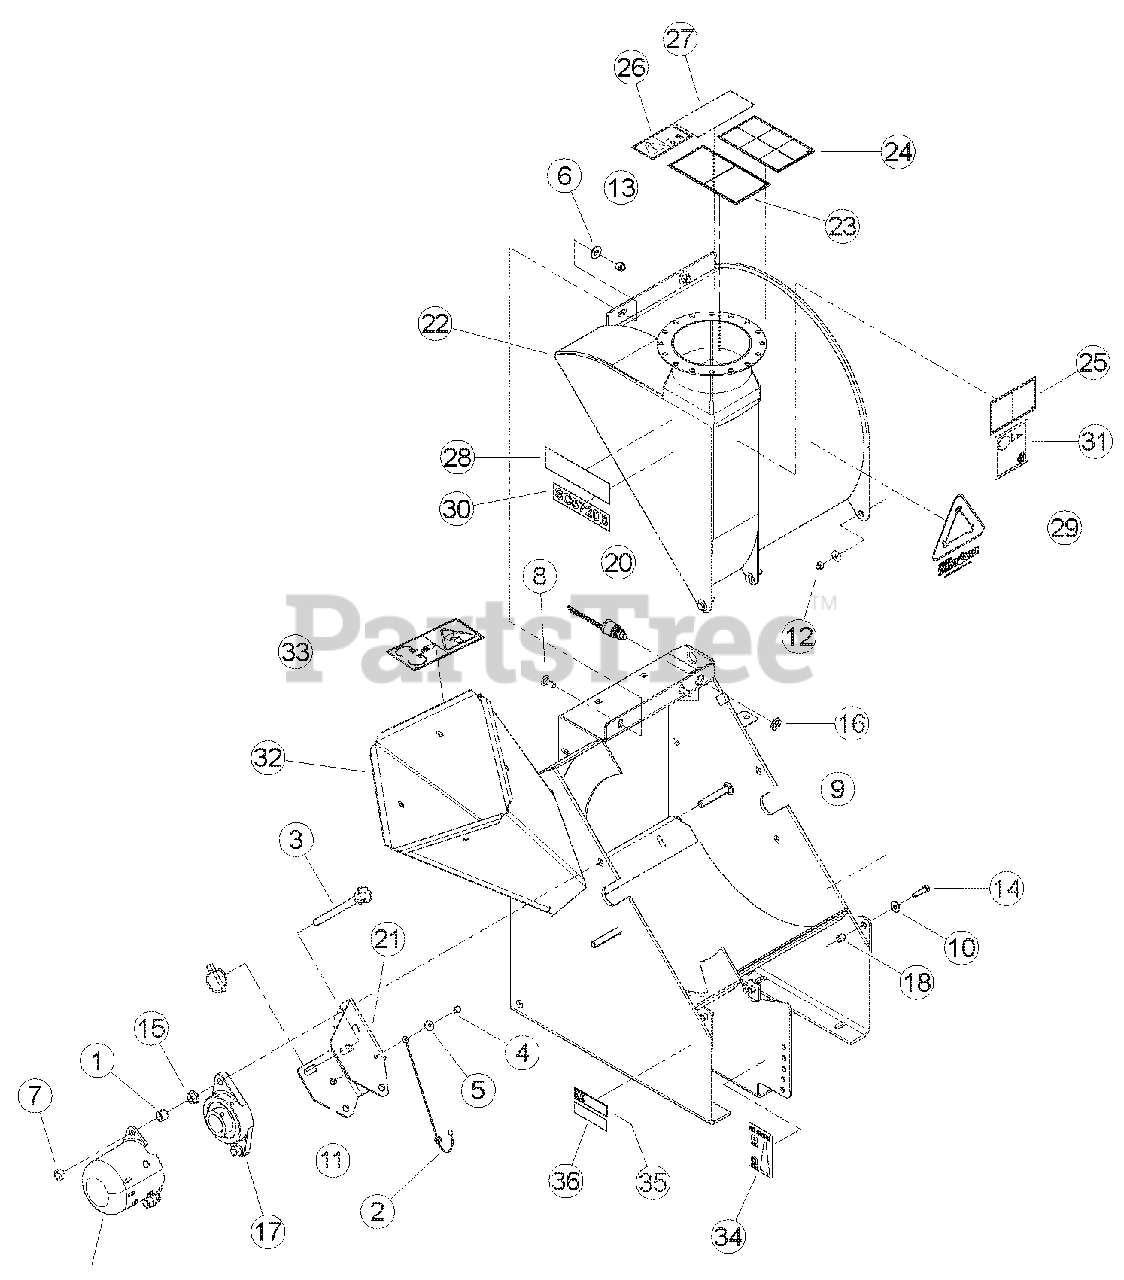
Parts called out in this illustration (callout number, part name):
1	BUSHING, 1/2ID X 3/4OD X 17/32 LNST
2	LANYARD, NYLON
3	PIN, HITCH 1/2 X 6-1/2 W LYNCH
4	BOLT, 1/4 X 3/4 HEX HD GR5 ZP
5	WASHER, 1/4 FLAT ZP
6	WASHER, 3/8 FLAT ZP
7	NUT, 1/2 CENTERLOCK GRB ZP
8	BOLT, 3/8 X 1 CRG GR5 NC ZP
9	BOLT, 1/2 X 3 CRG GR5 ZP
10	WASHER, 5/16 FLAT ZP
11	NUT, 1/4 NE NYLOCK ZP
12	NUT, 5/16 NE NYLOCK ZP
13	NUT, 3/8 NE NYLOCK ZP
14	BOLT, 5/16 X 1-1/4 GR5 HEX HD NC ZP
15	NUT, 1/2 SERR FLANGE NC ZP
16	NUT, 5/8-32 JAM
17	BEARING, 2 BOLT FLANGE 1-1/2" BORE
18	SPACER, .50 X .50
19	CAP, LARGE SHAFT
20	ASSEMBLY, SEALED SWITCH
21	PLATE, ROTOR LOCK
22	ASSEMBLY, HOUSING TOP 5" C/S/B, SERVICE PART
23	DECAL, KNIFE ACCESS ISO
24	DECAL, OPERATING INSTRUCTIONS ISO
25	DECAL, DISCHARGE ISO
26	DECAL, MAINTENANCE ISO
27	DECAL, MUTILINGUAL MANUAL
28	DECAL, ECHO BEARCAT 6.82 X 1.90
29	DECAL, SHRED IT
30	DECAL, MODEL SC5720B
31	DECAL, 120 DB
32	ASSEMBLY, CHIPPER BOTTOM, SERVICE PART
32	ASSEMBLY, CE CHIPPER BOTTOM, SERVICE PART
33	DECAL, BLADE DANGER ISO
34	DECAL, SHRED SIZE
35	DECAL, SC5720B INFORMATION
36	DECAL, ATLANTIC BRIDGE LTD INFO
